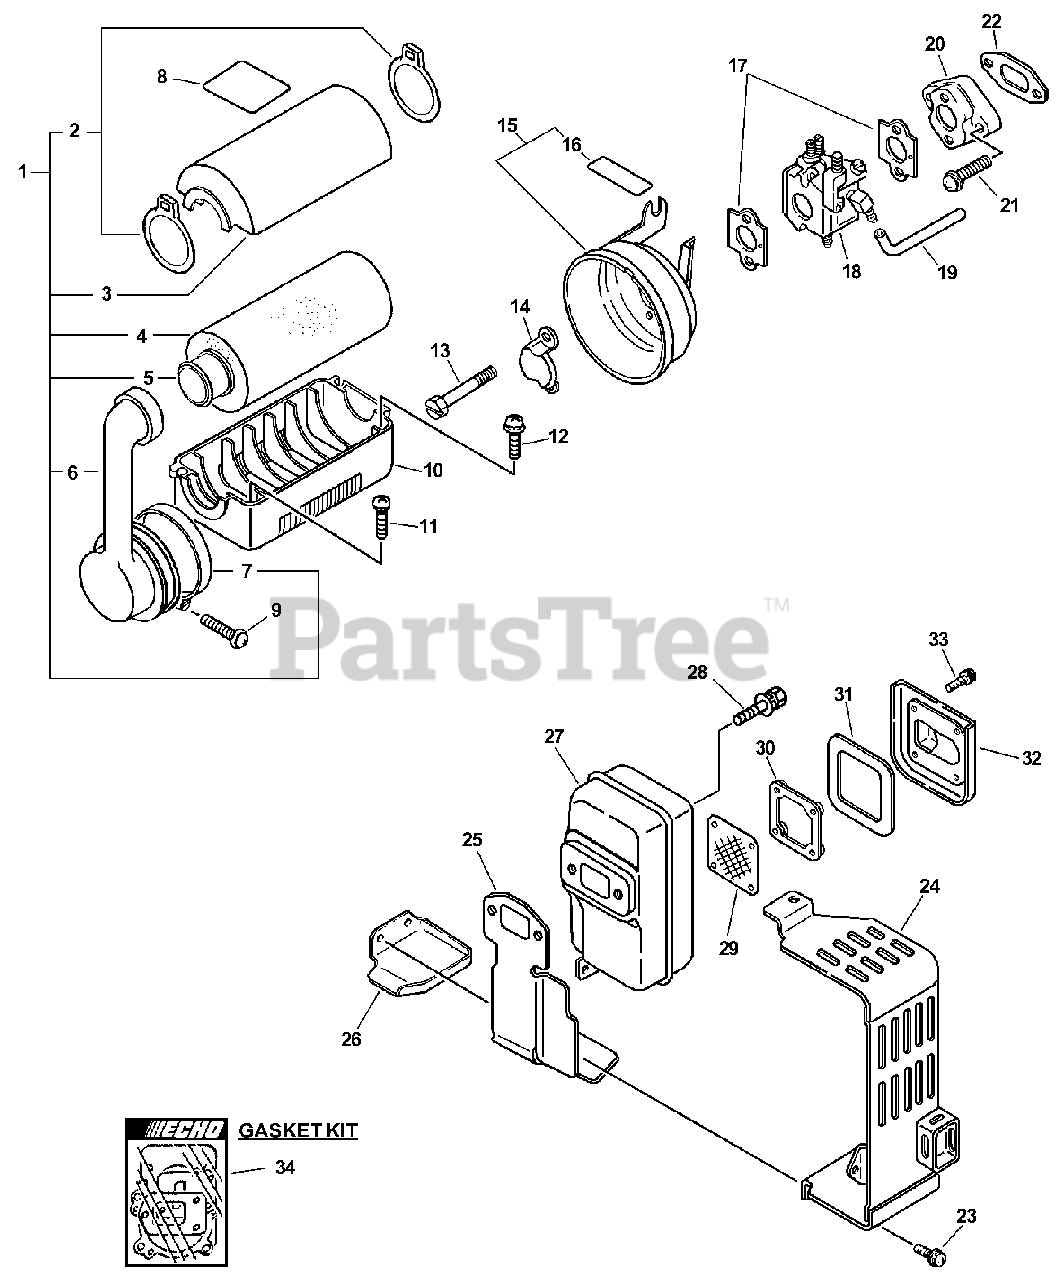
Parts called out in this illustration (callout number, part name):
1	AIR FILTER ASSY
3	COVER, AIR FILTER
4	FILTER, AIR
5	HOLDER, AIR FILTER
6	ADAPTER, INTAKE
8	LABEL - CAUTION
9	SCREW 5×30
10	CASE, AIR FILTER
11	SCREW 6×15
12	SCREW 6×20
13	SCREW 5×50
14	PLATE, PREVENT
15	CASE, AIR FILTER
16	LABEL, CHOKE
17	GASKET, CARBURETOR
18	CARBURETOR - WT-684
19	PIPE
20	INSULATOR
21	SCREW 6×25
22	GASKET, INTAKE
23	SCREW 5×14
24	COVER, MUFFLER
25	GASKET, EXHAUST
26	BRACKET, MUFFLER COVER
27	MUFFLER
28	BOLT 6×20
29	SCREEN KIT
30	SEAT, SCREEN
31	GASKET, EXHAUST
32	GUIDE, EXHAUST
33	SCREW 4×16
34	GASKET KIT
